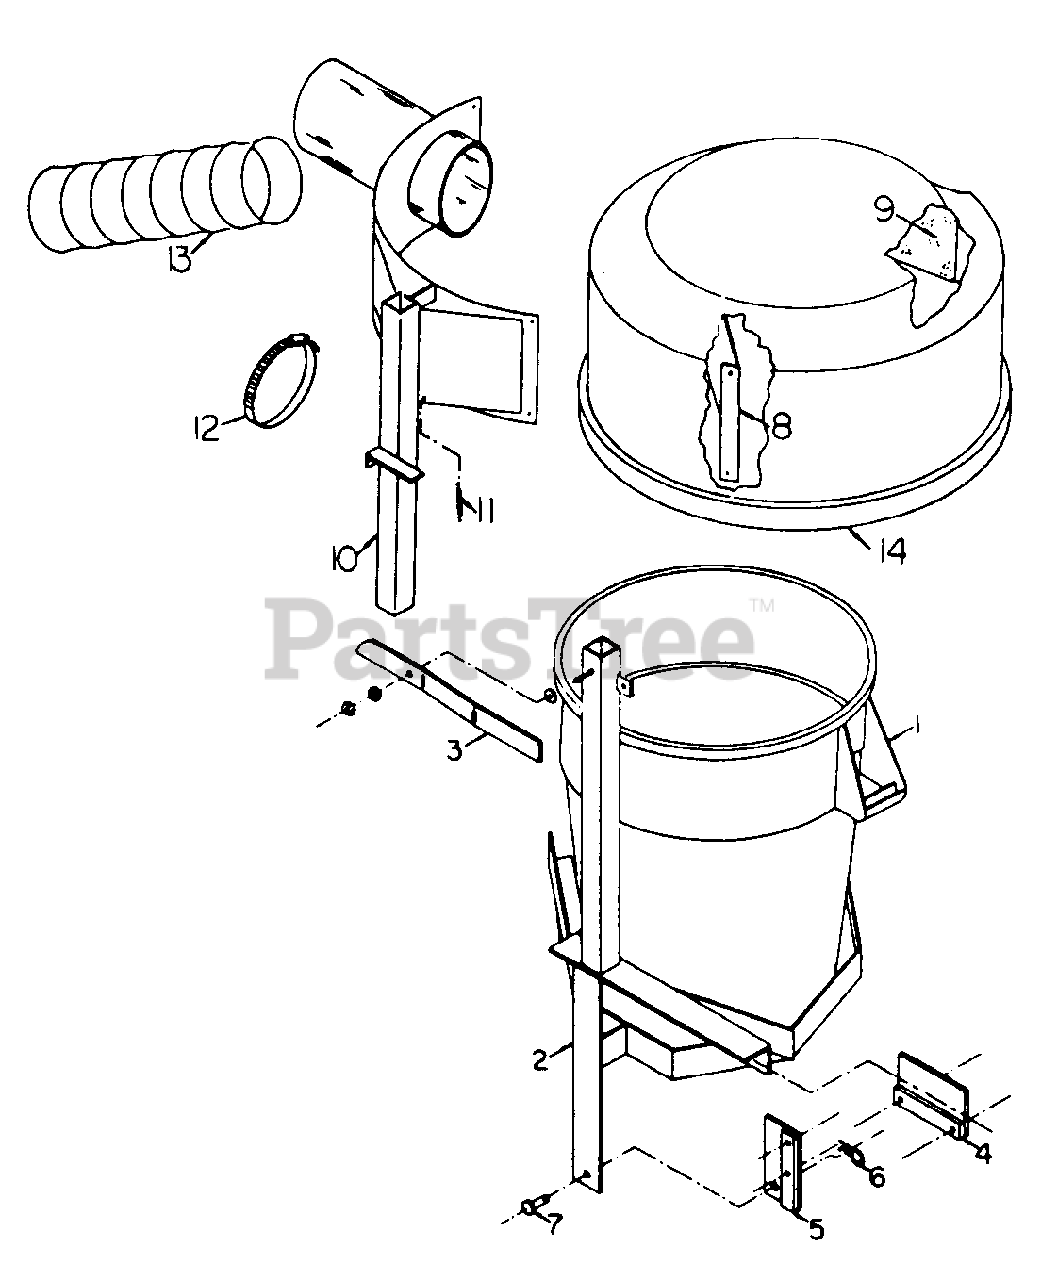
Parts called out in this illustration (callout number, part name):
3	Handle
4	Top Mount
6	Hair Pin Cotter, .120 x 2-1/2"
7	Clevis Pin, 1/2" x 1-1/2"
10	Barrel Lid Mount
13	Hose
